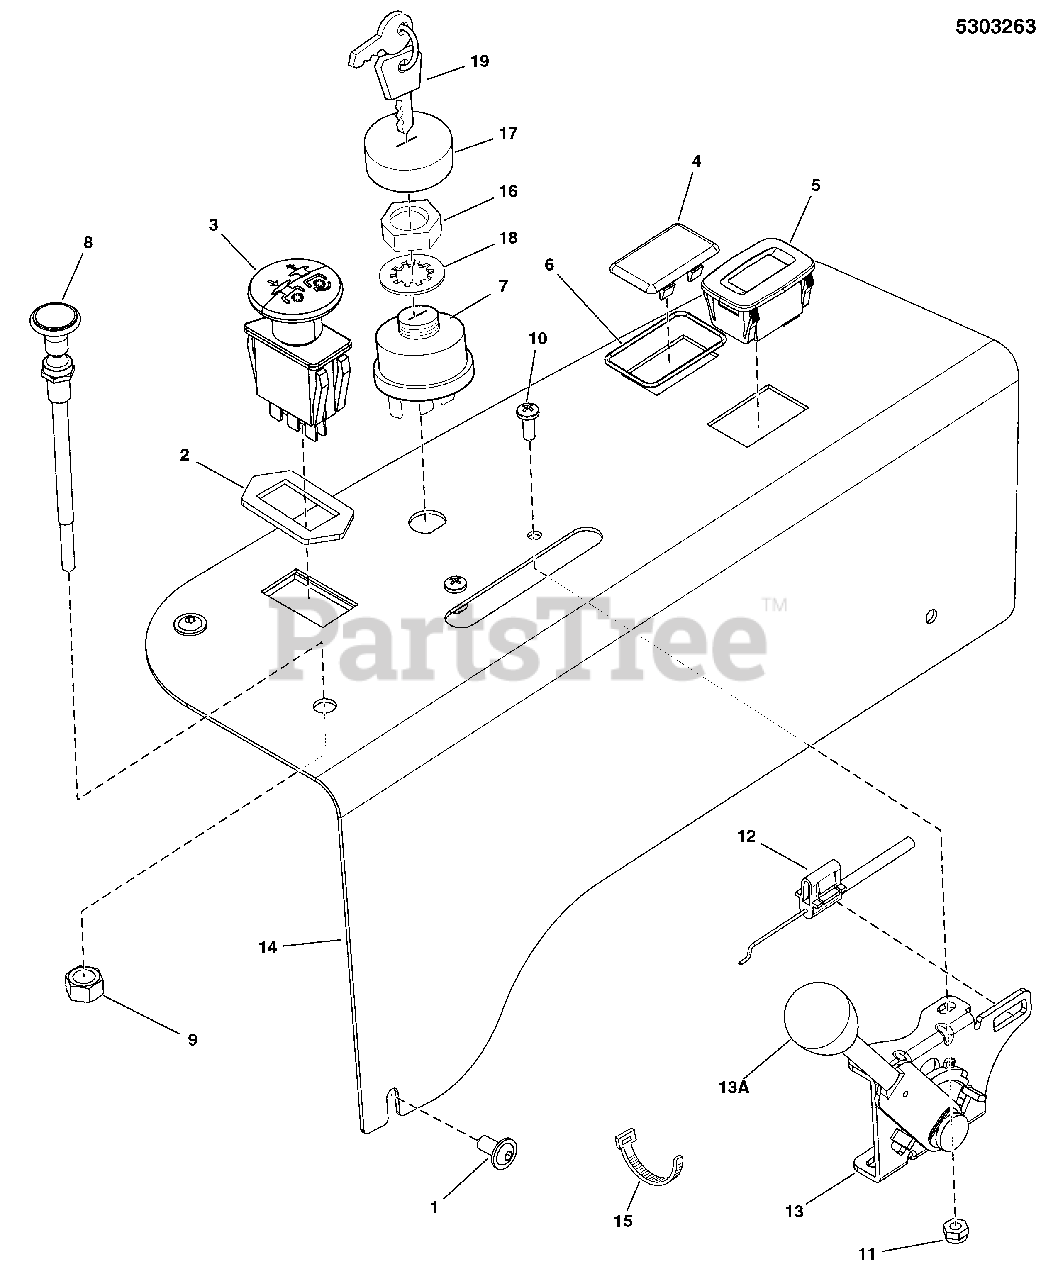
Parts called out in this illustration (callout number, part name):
1	SCREW, ALLEN HEAD 1/4-20 X .500 ZINC PHOS
2	RING, SWITCH RETAINER, PTO
3	SWITCH, Blade Engage
4	PLUG, Hole, Electric Lift (Hydro models only)
5	O-RING, 7/8" ID X 1/16" W
6	HOUR METER, ASSEMBLE
7	SWITCH ASSEMBLY, Ignition Indak No Keys/Hdwr
8	CABLE, CHOKE CONTROL, 51 (Z)
9	NUT, 3/8-24 HEX JAM (SV)
10	SCREW, #10-24 X 3/4", ROUND PHILLIPS
11	NUT, Nylock, #10-24, GR2
12	CABLE, THROTTLE, 42"
13	LEVER, THROTTLE CONTROL, HEAVY DUTY
13A	THROTTLE CONTROL HANDLE/KNOB
14	PLATE, CONTROL PANEL, IS600Z - BLK
15	TIE, 6" Self-Locking
16	NUT, Hex Flange, 5/8-32 IGN SW DIE CAST
17	COVER, Ignition Switch
18	LOCKWASHER, Internal Tooth, 5/8 Thin
19	KEYS, Ignition
